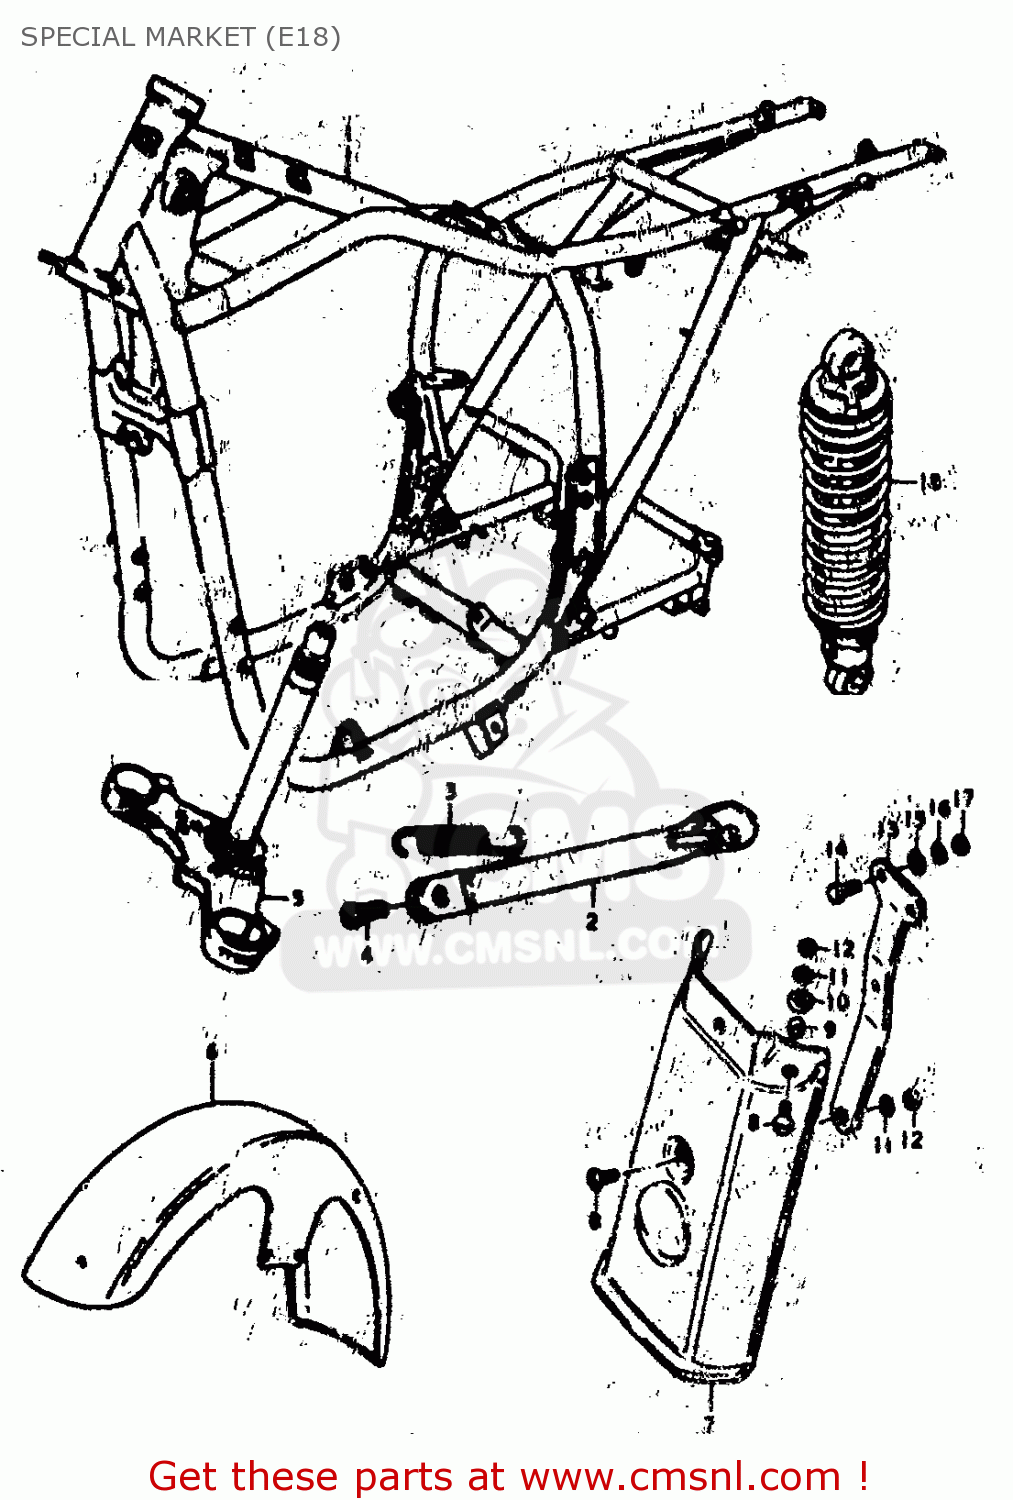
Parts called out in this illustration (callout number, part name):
1	FRAME
2	STAND,PROP
3	SPRING
4	BOLT
5	STEERING STEM
6	FENDER,FR
7	EXTENSION,REAR FENDER
8	SCREW (6X15)
9	SPACER(6.2X8.3X5.7)
10	WASHER(6.5X18X1)
11	LOCK WASHER
12	NUT
13	BRACE, REAR FENDER EXTENSION
18	SHOCK ABSORBER, REAR
